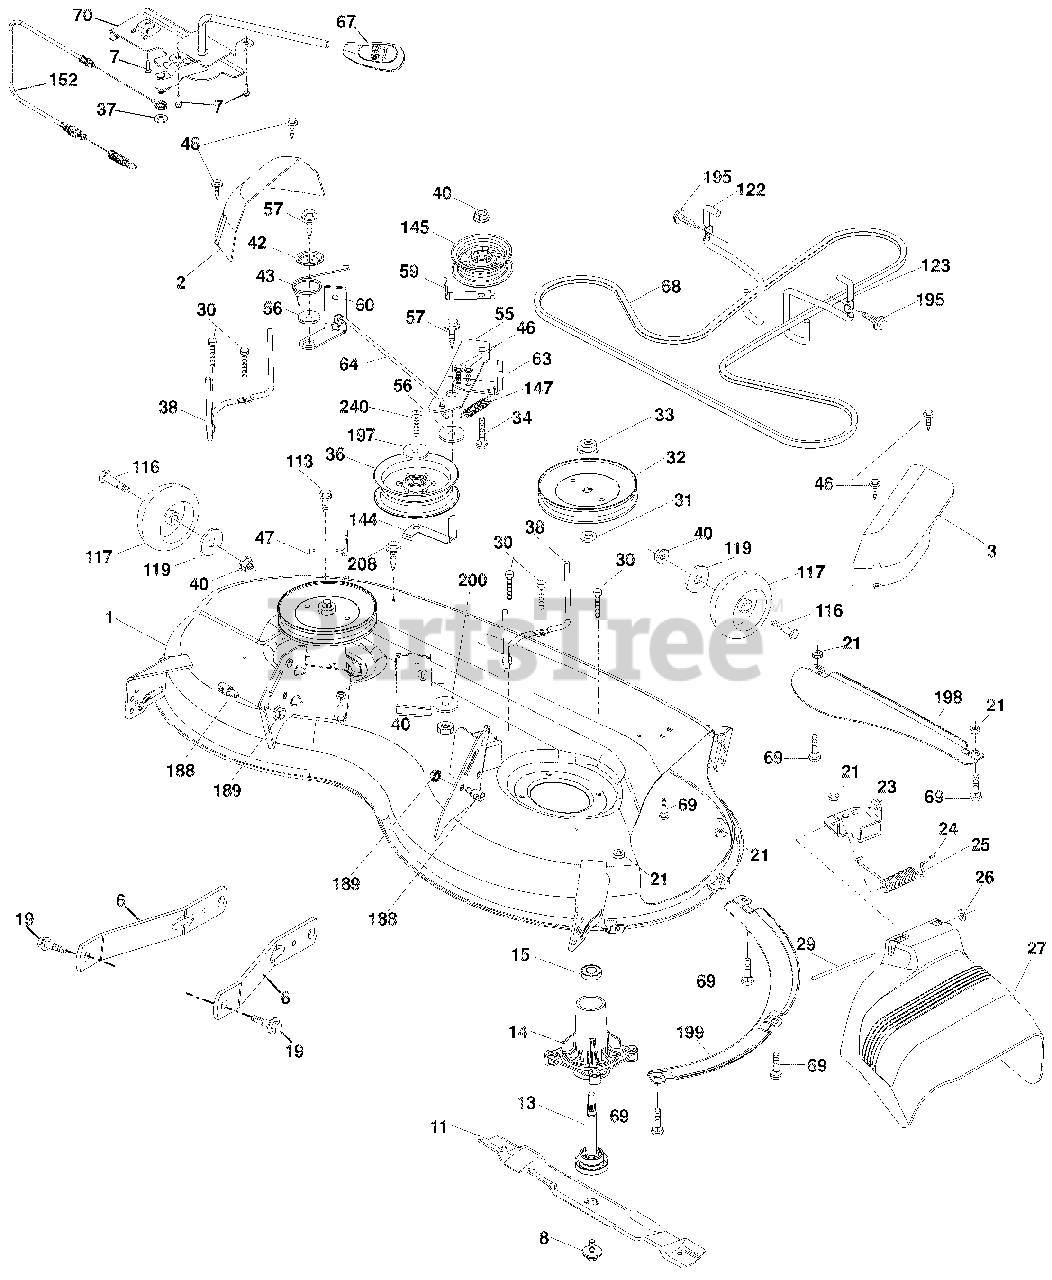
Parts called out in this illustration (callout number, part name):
1	DECK.WELDMENT.46"4GA WHL.MS422
1	DECK.SVC.46"HP.CC.4GWB.TEX.422
2	COVER.MANDREL.RH.46"
3	COVER.MANDREL.LH.46"
6	ARM.SUSPENSION.MOWER.REAR.LD
8	BOLT/WASHER ASM.7/16-20.UNF
11	BLADE.MOWER.46"HI LIFT BAGGER
13	SHAFT ASM.MNDRL.N/GREASEABLE38
14	HOUSING.MANDREL.4PT.SERVICE
15	BEARING.BALL.MANDREL
19	BOLT.SHOULDER
21	Nut, Hex, Crownlock 5/16-18
23	BRACKET.DEFLECTOR.38/42"2005
24	CAP.SLEEVE..80X.112.BLK.MOWER
25	SPRING.TORSION.DFL.38/42/46.GR
26	NUT.PUSH.PHOS.& OIL
27	SHIELD.DEFLECTOR.MOWER 46"BLK
29	ROD.HINGE.42/46"
30	SCREW.THD ROLL.DOD PT.HEX
31	WASHER.SPACER.MANDREL
32	PULLEY.MANDREL.5.438 PD.42"
32	MANDREL ASM.SUB.N-GRS.4 BOLT
32	pulley/nut/washer and blade bolt/washers not included)
33	NUT.FLANGE.LOCK.TOP
34	BOLT.CARR.SH.3/8-16X1-1/2.GR5
36	PULLEY.IDLER.4.50.RAW
37	WASHER.13/32 X 13/16 X 16 GA.
38	KEEPER.BELT.LH.MANDREL.42/46"
40	Nut, Hex, Flangelock 3/8-16
42	SPRING.TORSION.RETAINER
43	SPRING.TORSION.BRAKE
46	SCREW.THD.ROLL.1/4-20 X 5/8
47	BRACKET.CLUTCH.CABLE
55	IDLER.ARM
56	SPACER.RETAINER
57	SCREW.3/8-16X1.SMGML.TAP/R.BLK
59	GUARD.TUV.IDLER
60	ARM.BRAKE.MOWER.38/46"LH.TEX
63	ARM.BRAKE.(ZINC)
64	LINKAGE ASM.BRAKE.CLEAR ZINC
67	HANDLE.CLUTCH.CABLE.LT TEX.428
68	V-BELT.DRIVE.MWR.MECHANICL.46"
69	BOLT.RDHD.SQNK.5/16-18 X 5/8
70	SPRING.RETURN.CRUISE
113	BOLT.5/16-18HEX.WHS.HD.LCKSERR
116	BOLT.SHOULDER.3/8-16X3-5/8.GR5
117	WHEEL.GAUGE.RALLY.
119	WASHER.13/32 X 1-1/4 X 12 GA.
122	KEEPER.BELT.ENGINE.LH.LT.TEX
123	KEEPER.BELT.ENGINE.RH.LT.TEX
144	KEEPER.BELT.MOWER
145	PULLEY IDLER
147	SPRING.RETURN.DECK.38/46"
152	CABLE.CLUTCH.MANUAL.W/SPR.
188	STUD.FASTNER.W/'D'ANTI-ROTATIO
189	Nut, Lock Hex Flange 5/16-18 u
195	SCREW.HEXWSH THDR3/8-16X3/4.BL
197	Washer 13/32 x 13/16 x 12 Ga.
198	BAFFLE.CENTER.FRONT
199	BAFFLE.FRONT.RH
200	WASHER.13/32 X 1 X 1/2.11GAHRD
208	SCREW.THDROL.3/8-16X1/2.TYT.BL
240	BOLT.FIN.HEX.3/8-16X 2-1/4 GR5
